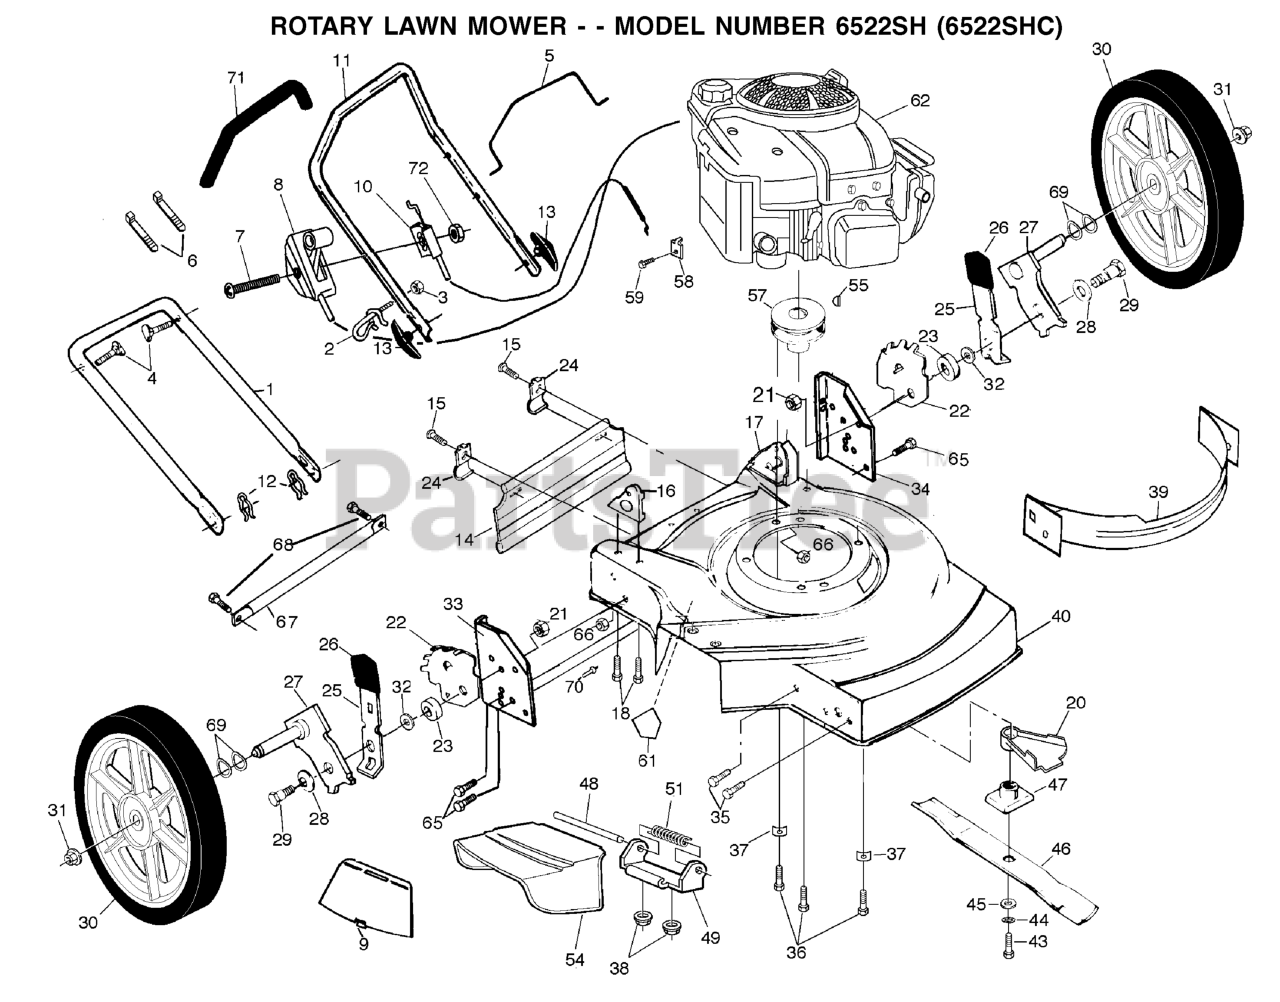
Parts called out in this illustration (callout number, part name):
1	LOWER HANDLE
2	ROPE, GUIDE
3	NUT
4	HANDLE BOLT
6	TIE GUIDE
7	SCREW 1/4-20 X 2.12
8	THROTTLE CONTROL
9	REPL BY 532 12 54-20
10	CABLE.MZR.51.RT.SP./PU.
11	UPPER HANDLE
12	HAIRPIN COTTER
13	HANDLE KNOB
14	REAR SKIRT
15	TAPPING SCREW
16	HANDLE BRACKET ASM. RH
17	HANDLE BRACKET ASM. LH
18	SCREW.5/16-18X3/4
20	DEBRIS SHIELD
21	LOCKNUT PM
22	WHEEL ADJ BRKT
23	RP SPACER HT ADJ
24	BRACKET DEFL PM
25	SELECTOR SPRING
29	BOLT
31	HEX FLANGE LOCKNT
32	WASHER.FLAT.1/2
35	SCREW 1/4X20
36	BOLT 3/8-16X1-1/8
37	WASHER.ENGINE.BZP
38	NUT
39	FRONT BAFFLE KIT
43	SCREW, HEX HD 3/8-24 X 1-3/8
44	LOCKWASHER
45	WASHER,HARDEN
47	BLADE ADAPTOR
48	ROD.HINGE.COMBI-C
49	BRACKET PM
54	DISCHARGE GUARD
55	HI PRO KEY PM WSL
57	ENGINE.PULLEY.FWG
58	WASHER
59	SCREW.HEX.HEAD.WASHER.10-16
61	DECAL HYT
66	LOCKNUT PM
69	WAVE WASHER
70	RIVET BLIND
71	GRIP.HANDLE.FOAM
72	NUT
